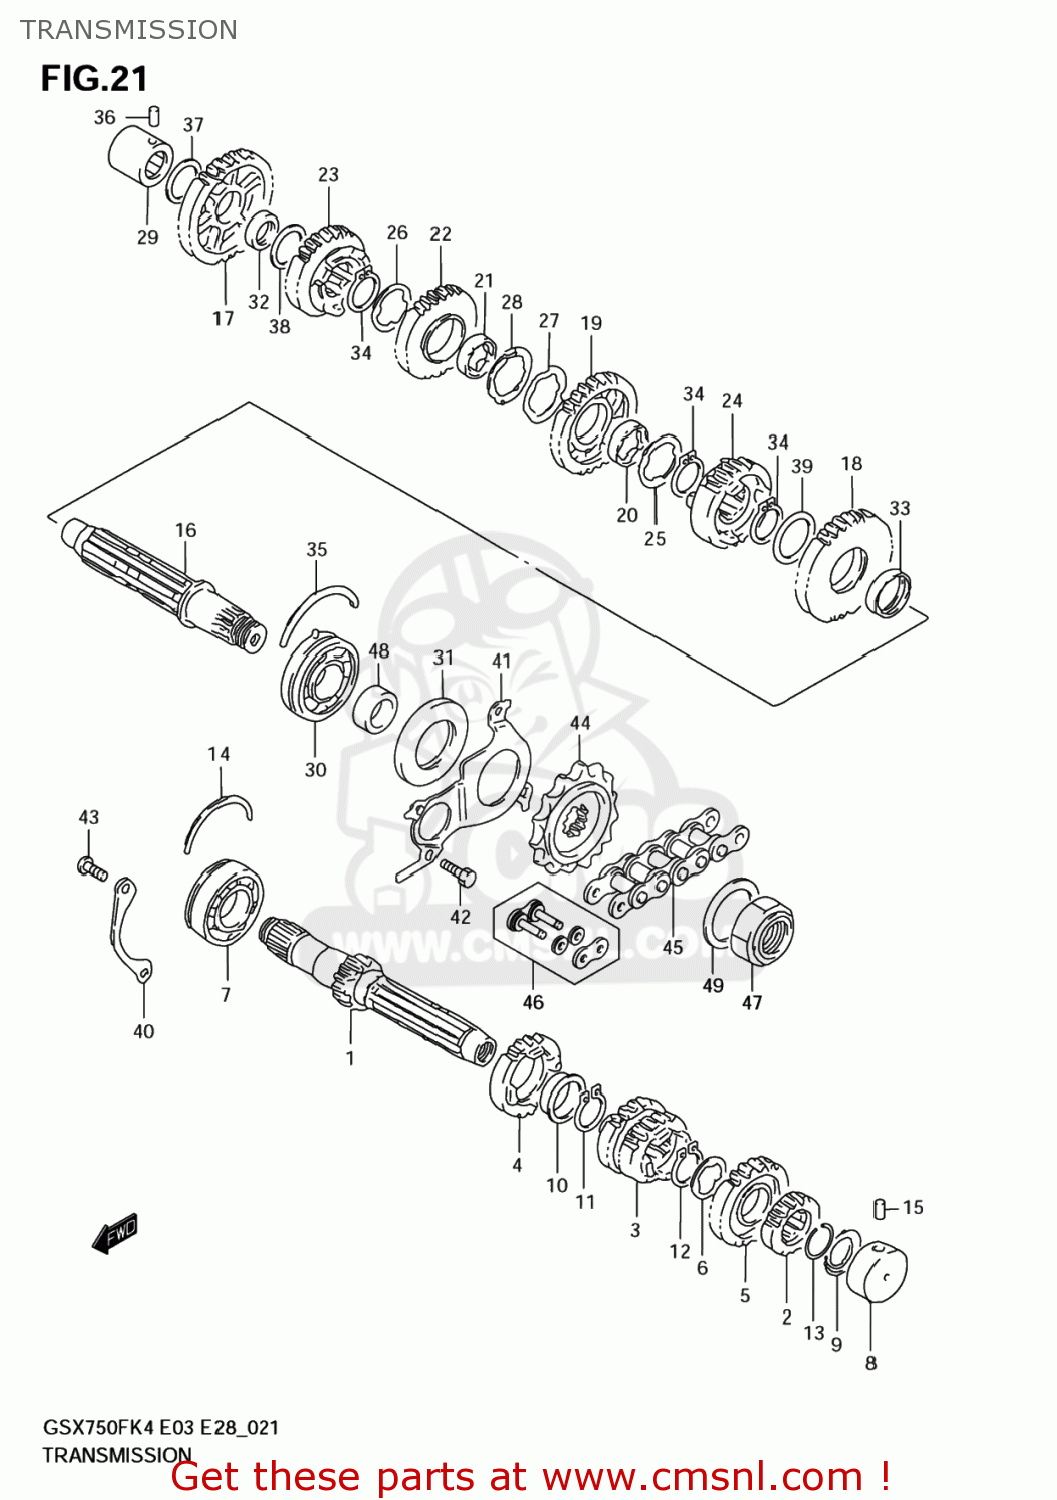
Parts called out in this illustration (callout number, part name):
1	SHAFT,COUNTER(NT:12)
2	GEAR,2ND DRIVE(NT:16)
3	GEAR,3RD & 4TH DRIVE(NT:17/20)
4	GEAR,5TH DRIVE(NT:22)
5	GEAR,6TH DRIVE(NT:21)
6	WASHER,LOCK
7	BEARING(25X62X17)
8	BEARING(20X34X17.5)
9	SEAL,OIL(20X31.2X2.7)
10	BUSH
11	RING,SNAP
12	RING,SNAP
13	CIRCLIP
14	C RING
15	PIN
16	SHAFT,DRIVE
17	GEAR,1ST DRIVEN(NT:37)
18	GEAR,2ND DRIVEN(NT:33)
19	GEAR,3RD DRIVEN(NT:28)
20	BUSH
21	BUSH
22	GEAR,4TH DRIVEN(NT:28)
23	GEAR,5TH DRIVEN(NT:27)
24	GEAR,6TH DRIVEN(NT:23)
25	WASHER,LOCK
26	WASHER,LOCK
27	WASHER,LOCK
28	WASHER
29	BEARING(20X34X20)
30	BEARING(25X62X21.6)
31	SEAL,OIL(34X62X6)
32	BUSH(22X26X9)
33	BUSH(28X32X9.5)
34	CIRCLIP
35	C RING
36	PIN
37	SHIM(20X34X1)
38	SHIM(22X34X1)
39	SHIM(28X38X1)
40	RETAINER,CNTR SHAFT BEARING
41	RETAINER,DRIVE SHAFT OIL SEAL
42	BOLT
43	SCREW(6X12)
44	SPROCKET,ENGINE(NT:15)
45	CHAIN,DRIVE(116LE)
46	JOINT SET,CHAIN
47	NUT
48	SPACER(25X34X17.5)
49	SHIM(25X40X1.5)
